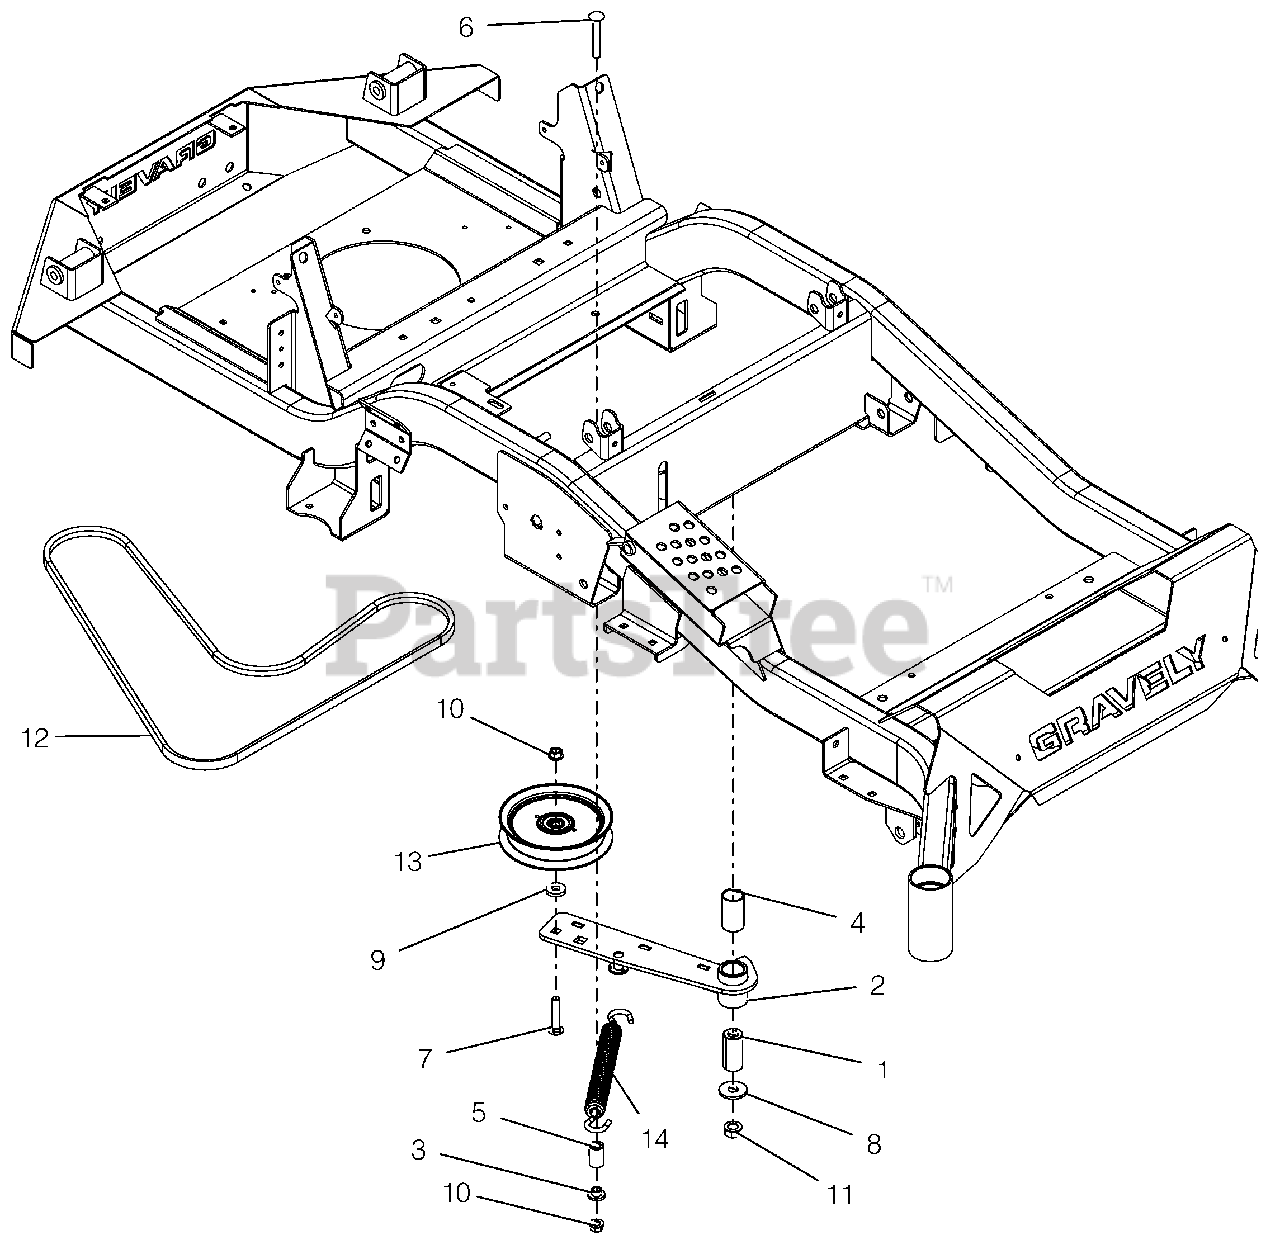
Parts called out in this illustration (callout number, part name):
1	BSHG, SPCR .502X.997X2.03 PM
2	WLDMT, HYDRO DRIVE IDLER ARM
3	BSHG-FLG .385X.500X.875X.406
4	BSHG, 1.00X1.125X1.937
5	BUSHING, SLV .380X.750X1.190
6	BLT-RDHDSQSHK, 38-16X2.50 G5YZ
7	@BLT-RDHDSQNK .38-16X2.00 G5YZ
8	WSHR-FL-STL.511X1.441X.125 YWZ
9	WSHR-FL-STL .406X1.00X.188 YWZ
10	@NUT-LK-TOP-FLG .38-16 YWZC
11	@NUT-LK-TOP-FLG .50-13 YWZC
12	V-BELT, 4L-WRAPPED
13	IDLER, FLAT 5.00"
14	SPRING, EXTENSION
